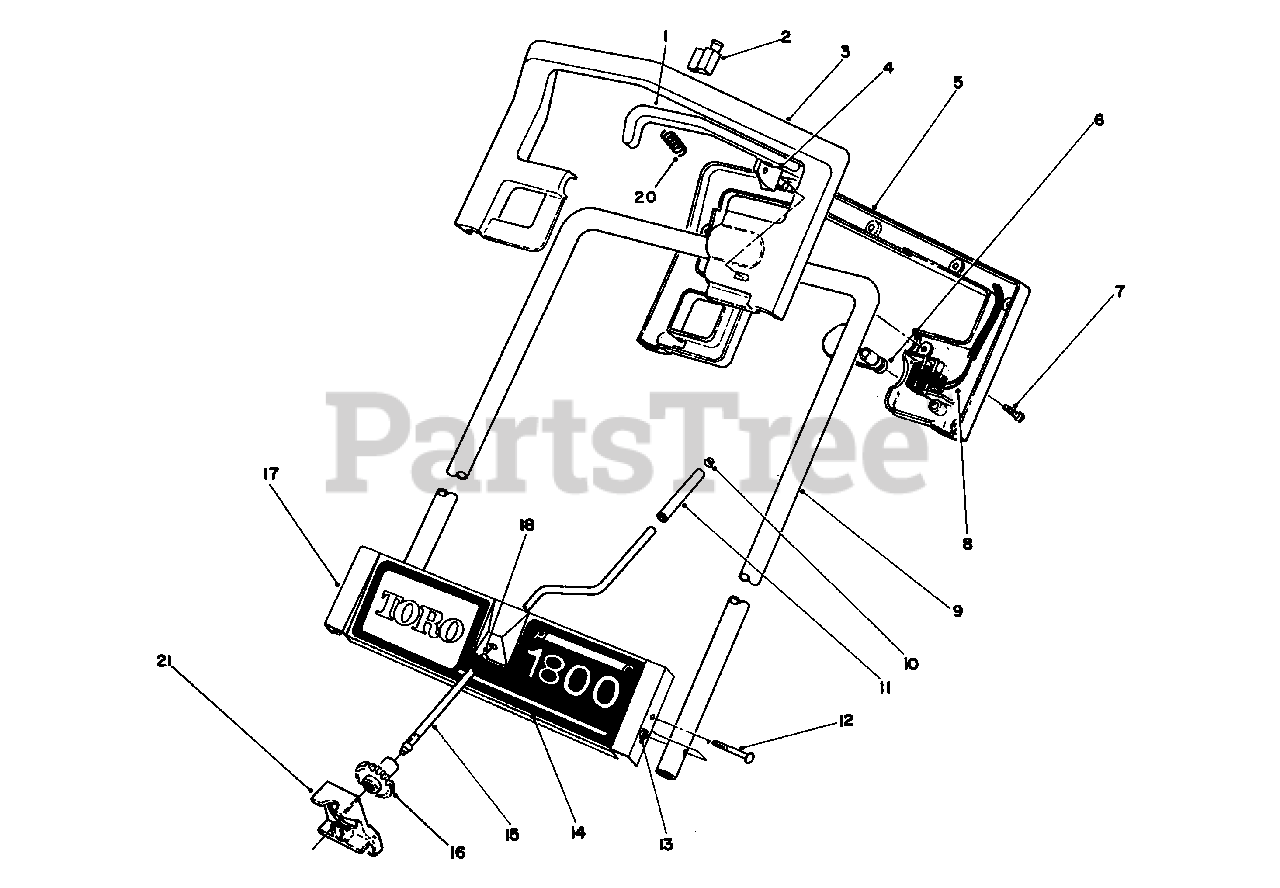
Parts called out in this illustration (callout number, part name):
1	Bar-Switch
2	Switch
3	Handle-Upper Control
5	Handle-Lower Control
6	Tab-Lock
7	Screw-Pan Hd. Form.
8	Cord-Supply
9	Tube-Upper Handle
10	Push Nut
11	Sleeve-Chute Crank
12	Screw-Hex. Hd. Mach.
13	Nut-Lock
14	Decal-Escutcheon
15	Rod-Chute Crank
16	Gear-Chute Crank
17	Plate-Escutcheon
18	Bushing-Snap In
21	Brake-Gear
